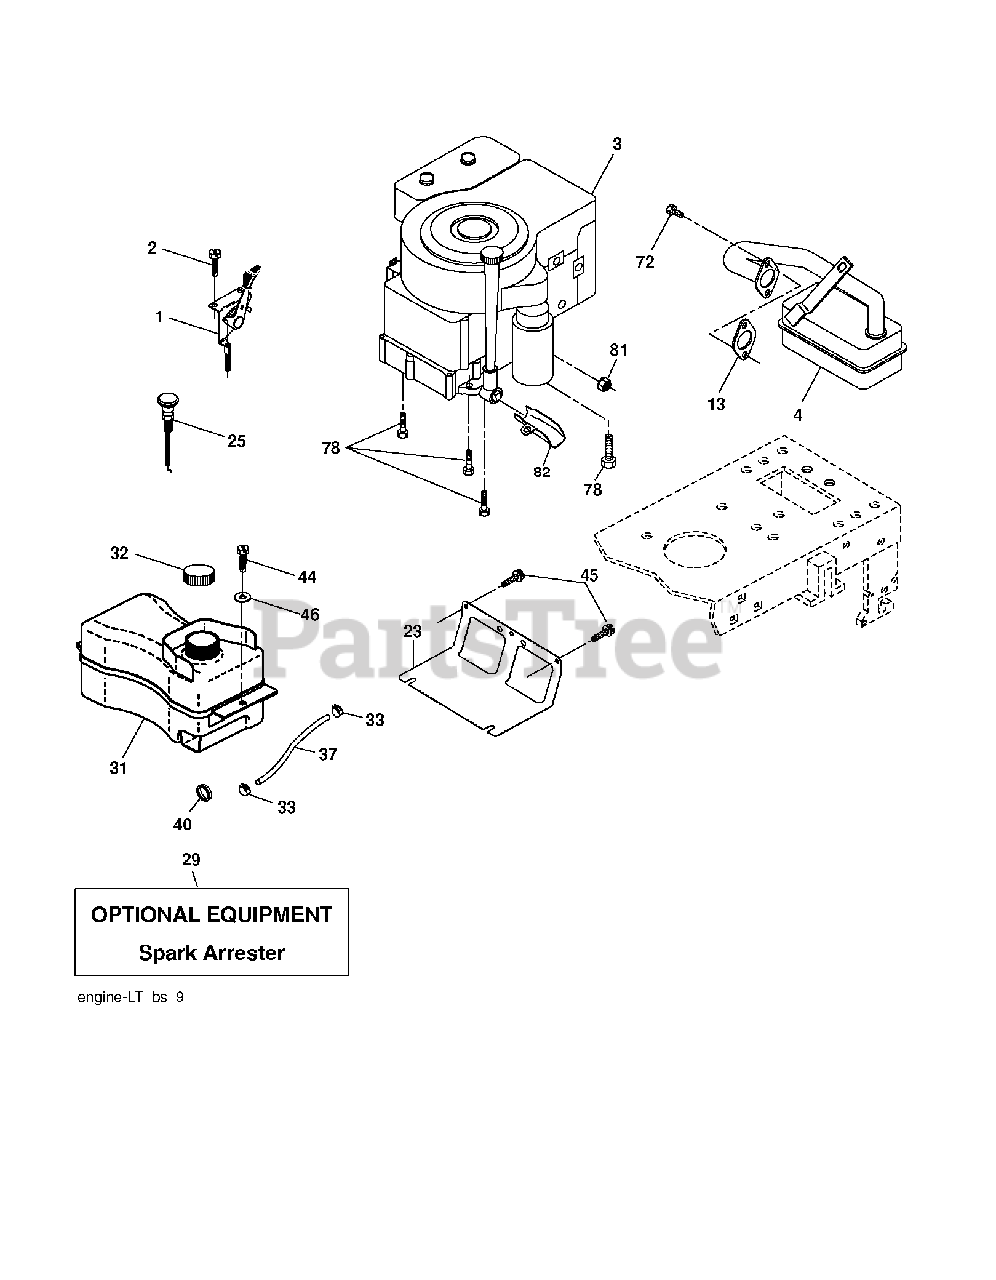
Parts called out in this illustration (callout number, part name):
1	CONTROL TH/CH FLAG
2	SCREW
13	REPL BY 532 27 22-93
23	SHEILD.BROWNING.DBR.GUARD
25	KNOB.ERGO.EXTENDED.RED (1 2)
29	ARRESTER SPARK (OPTIONAL)
32	CAP ASM.FUEL.2.25"FR.
37	LINE.FUEL.20
44	SCREW HEXWSHR 1/4-20X3/4
45	SCREW, 3/8-16X3/4
46	WASHER
72	SCREW.SOCKET HD.5/16-1
81	NUT
122	EXTENSION DRAIN OIL
